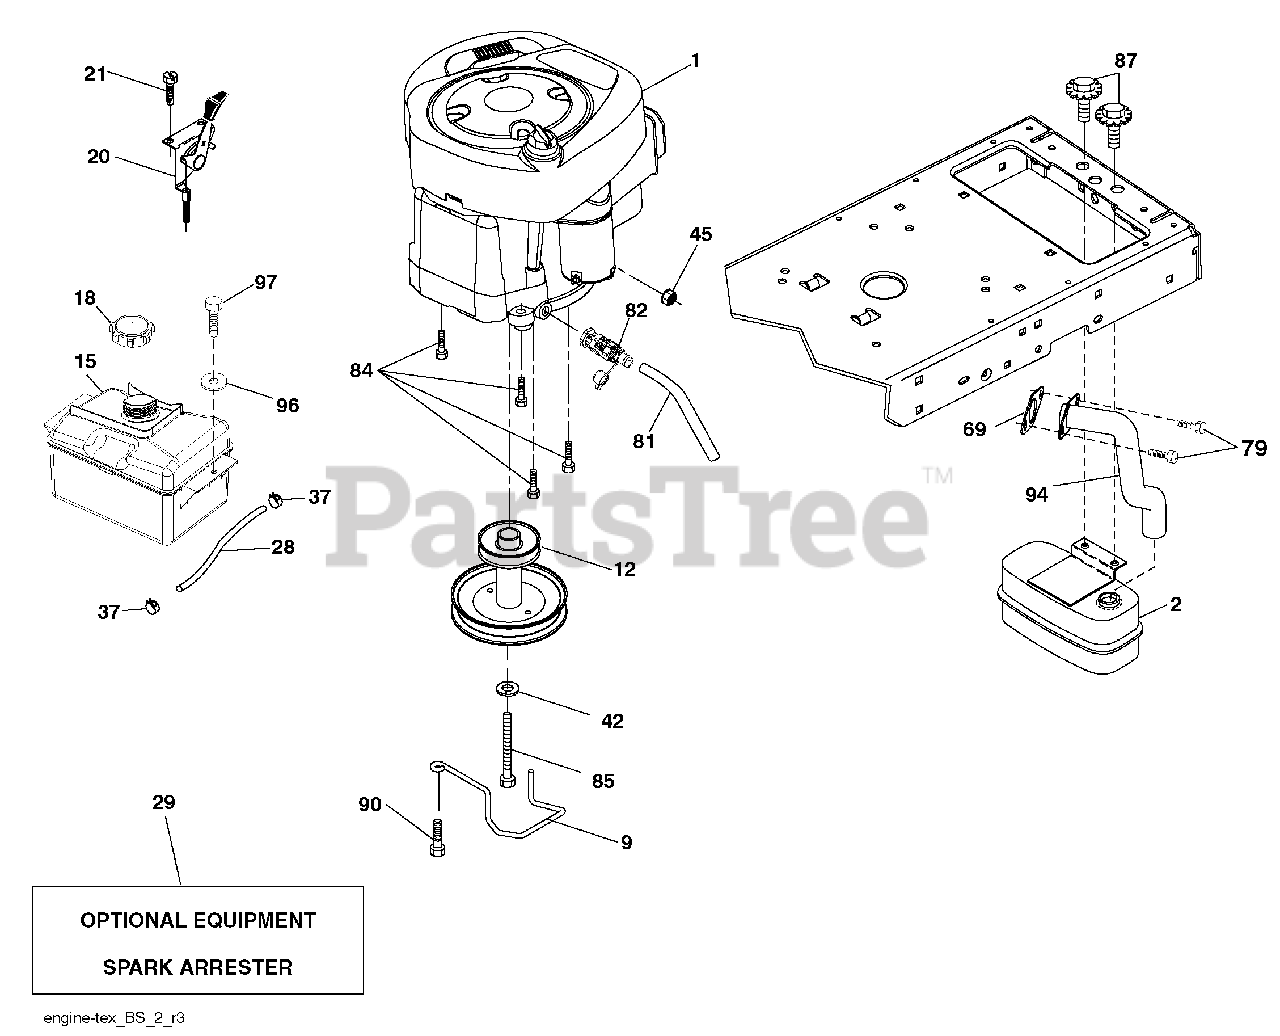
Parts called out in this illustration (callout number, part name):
9	Keeper Belt Engine
12	Pulley Engine
15	Tank Fuel
18	Cap Asm
20	Control Throttle
21	Screw #10 x 0.750 BOS Thread
28	Fuel Line
29	Spark Arrester Kit
37	Clamp Hose
42	Washer Lock 7/16
45	Nut Keps Hex 1/4-20 unc
69	Gasket
79	Screw 5/16-18 x 3/4
81	Tube Drain Oil Easy
82	Valve Drain Oil
84	Screw 3/8-16 x 1/4
85	Bolt Hex 7/16-20 x 4 Gr. 5
87	Bolt 5/16-18 unc x 3/4 w/sems
90	Screw 3/8-16 x 1
94	Exhaust Tube
96	Washer 9/32 x 7/8 x 16 Ga.
97	Screw 1/4-20 x 3/4
